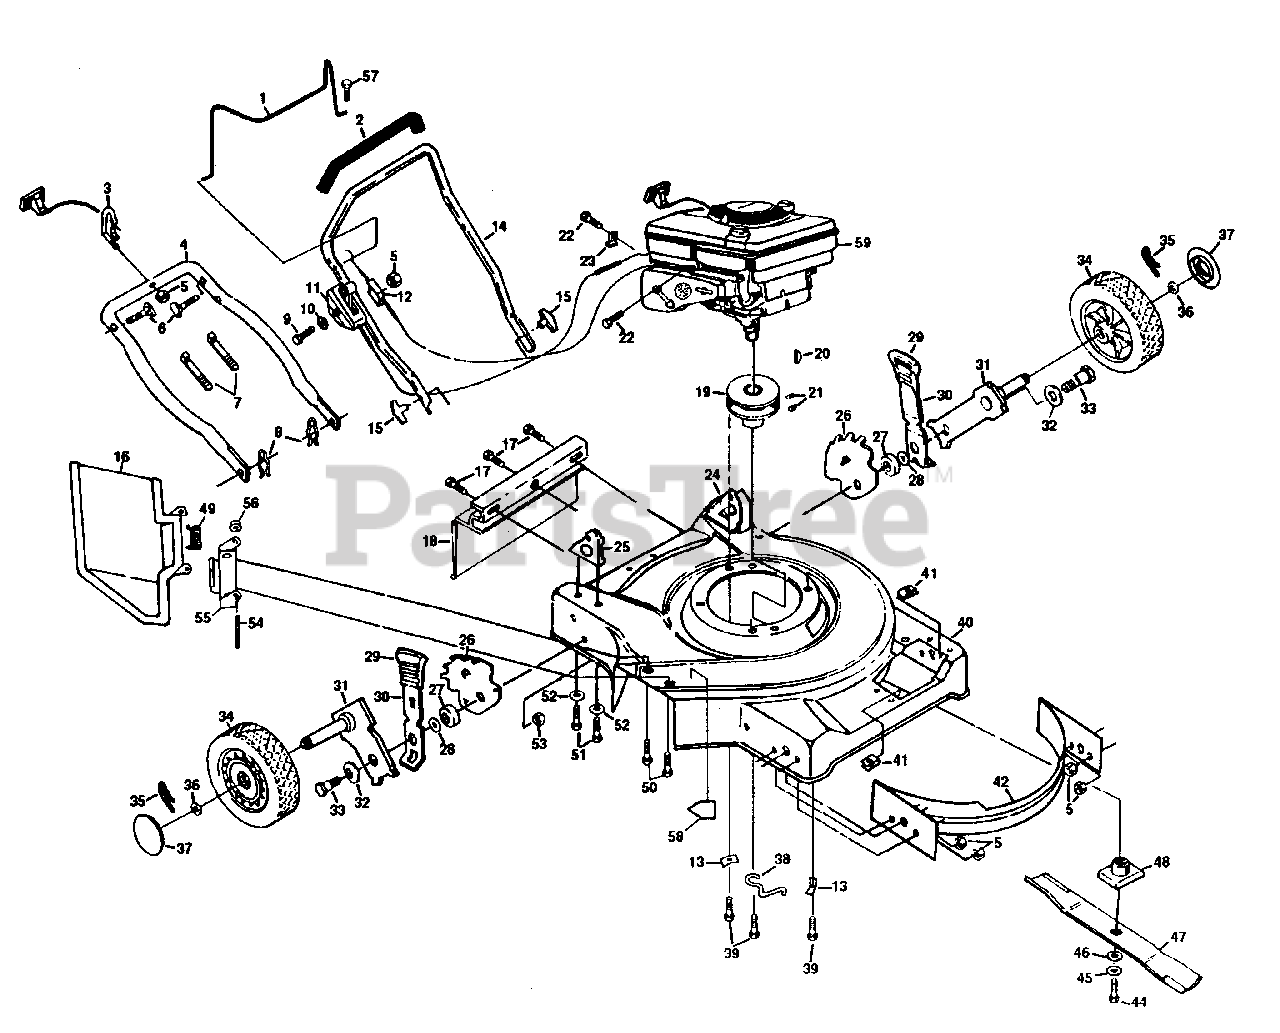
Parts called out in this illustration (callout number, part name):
1	Control Bar (AYP part number)
2	Handle Grip (AYP part number)
3	Rope Guide (AYP part number)
4	Lower Handle (AYP part number)
5	Locknut 1/4-20 (AYP part number)
6	Handle Bolt
7	Wire Tie (AYP part number)
8	Hairpin Cotter (AYP part number)
9	Machine Screw 1/4-20 x 2-1/8 (AYP part number)
10	Washer 9/32 x 5/8 x 1/16 (AYP part number)
11	Deluxe Throttle Control
12	Engine Zone Control Cable (AYP part number)
13	Engine Washer (AYP part number)
14	Upper Handle (AYP part number)
15	Handle Knob (AYP part number)
16	Discharge Guard
17	Hex Washer Head Tapping Screw #10-24 x 1/2 (AYP part number)
18	Rear Skirt (AYP part number)
19	Engine Pulley (AYP part number)
20	Hi Pro Key #HP-505 (AYP part number)
21	Set Screw 1/4-20 x 5/16 (AYP part number)
22	Thread Rolling Screw #10-32 x 5/8 (AYP part number)
23	Cable Clamp (Engine) (AYP part number)
24	Handle Bracket Assembly (Left) (AYP part number)
25	Handle Bracket Assembly (Right) (AYP part number)
26	Wheel Adjuster Bracket (AYP part number)
27	Spacer (AYP part number)
28	Flat Washer 3/8 (AYP part number)
29	Selector Knob (AYP part number)
30	Selector Spring (AYP part number)
31	Axle Arm Assembly (AYP part number)
32	Belleville Washer 1/2 (AYP part number)
33	Shoulder Bolt 3/8-16 (AYP part number)
34	Wheel & Tire Assembly (Rear) 8.00 x 1.75 (AYP part number)
35	Retainer Clip (AYP part number)
36	Washer 1/2 (AYP part number)
38	Belt Snubber (AYP part number)
39	Hex Head Thread Rolling Screw 3/8-16 x 1-1/8 (AYP part number)
40	Lawn Mower Housing Kit (Inc. 58)
41	U-type Speed Nut (AYP part number)
42	Front Baffle (AYP part number)
44	Hex Head Machine Screw 3/8-24 x 1-3/8
45	Helical Lockwasher 3/8 (AYP part number)
46	Hardened Washer (AYP part number)
47	22" Blade
48	Blade Adapter
49	Torsion Spring (AYP part number)
50	Hex Head Thread Rolling Screw w/Sems 1/4-20 (AYP part number)
51	Thread Cutting Screw 5/16-18 x 3/4 (AYP part number)
52	Washer 5/16 (AYP part number)
53	Locknut 3/8-16 (AYP part number)
54	Hinge Rod (AYP part number)
55	Housing Bracket (AYP part number)
56	Push-on Speed Nut (AYP part number)
57	Self-tapping Screw #10-24 x 5/8 (AYP part number)
58	Danger Decal (Housing) (AYP part number)
